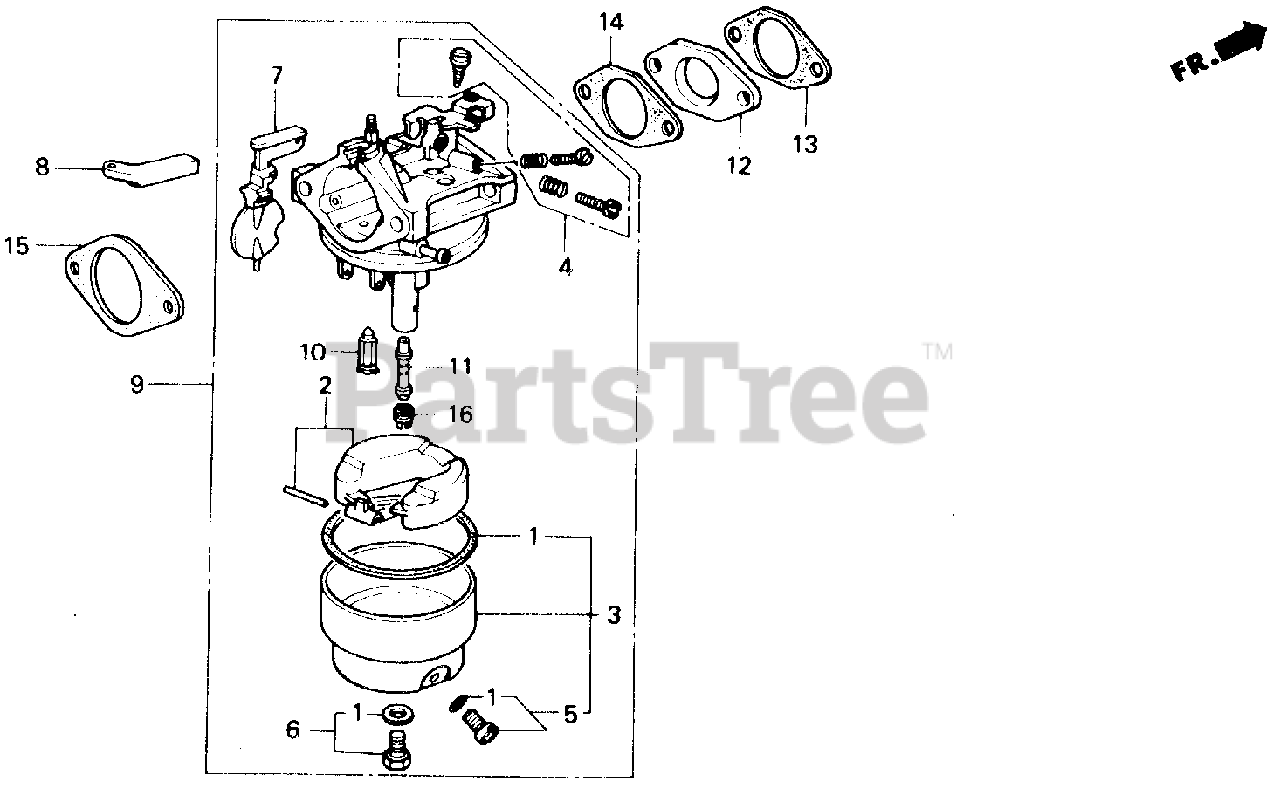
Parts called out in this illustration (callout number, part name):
1	GASKET SET
3	CHAMBER SET, FLOAT
4	SCREW SET A
5	SCREW SET, DRAIN
6	SCREW SET
8	ARM, CHOKE LEVER
9	CARBURETOR ASSY. (BB30E A)
9	CARBURETOR ASSY. (BB28A H)
10	VALVE, FLOAT
11	NOZZLE, MAIN
12	INSULATOR, CARBURETOR
13	GASKET, INSULATOR
14	GASKET, CARBURETOR
15	GASKET, AIR CLEANER
16	JET, MAIN (#60)
16	JET, MAIN (#62)
16	JET, MAIN (#65)
16	JET, MAIN (#68) Use from Engine SN 6122041.
16	JET, MAIN (#70)
16	JET, MAIN (#70) Use from Engine SN 6122041.
16	JET, MAIN (#72)
